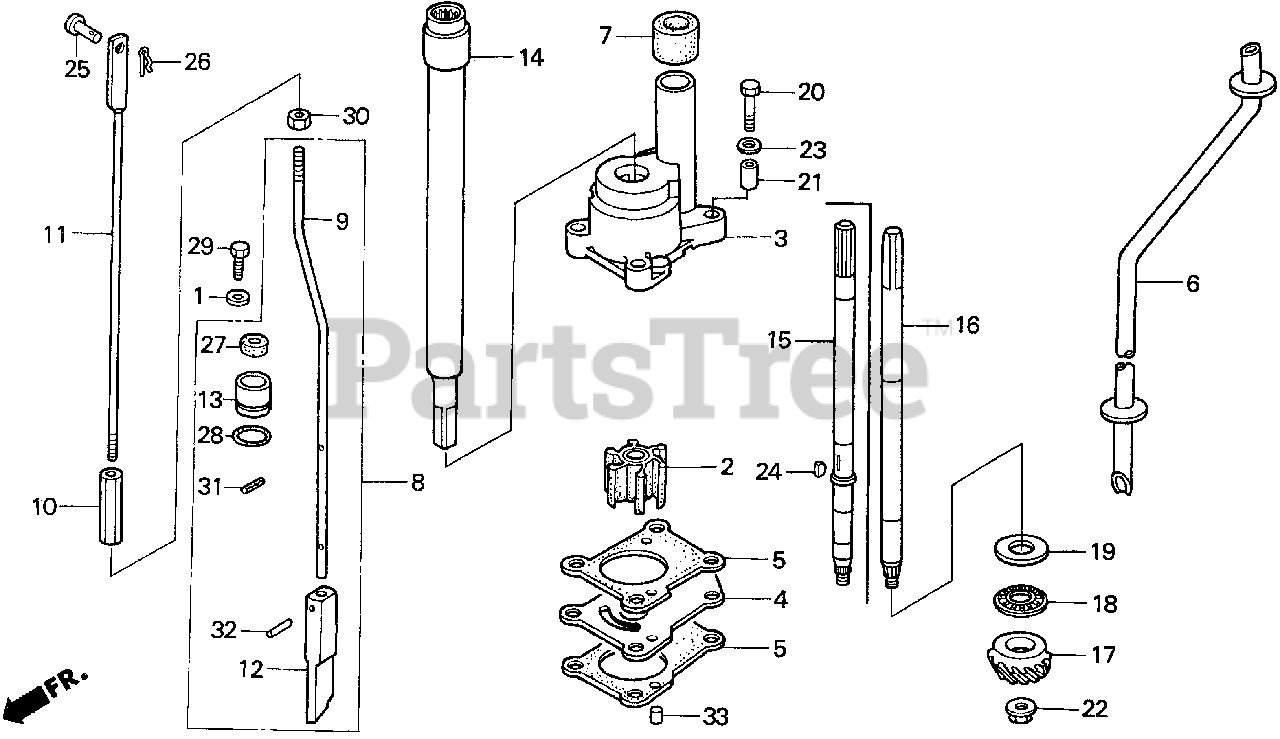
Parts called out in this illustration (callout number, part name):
1	WASHER, PLAIN (6MM)
1	WASHER, FRICTION
2	IMPELLER, PUMP
3	HOUSING, IMPELLER
4	COVER, IMPELLER
5	GASKET, IMPELLER
6	TUBE, WATER (UL)
7	RING, WATER TUBE SEAL
8	ROD B, SHIFT (UL)
9	ROD B, SHIFT (UL)
10	JOINT, SHIFT ROD
11	ROD A, SHIFT
13	HOLDER, SEAL
15	SHAFT, VERTICAL (UL)
17	PINION (13T)
18	WASHER A, THRUST BEARING (2.00MM)
19	WASHER A, THRUST BEARING (3.00MM)
19	WASHER B, THRUST BEARING (3.03MM)
19	WASHER C, THRUST BEARING (3.06MM)
19	WASHER D, THRUST BEARING (3.09MM)
20	BOLT, HEX. (6X28)
21	COLLAR B, DISTANCE
22	NUT, SPECIAL FLANGE (8MM)
23	WASHER, PLAIN (6MM)
24	KEY, WOODRUFF (16X12)
25	PIN (5X28)
26	PIN, SPLIT (2.0)
27	SEAL, WATER (6MM)
28	O-RING (15X2.5)
29	BOLT, HEX. (6X12)
30	NUT, HEX. (6MM)
31	PIN, SPRING (2.5X12)
32	ROLLER (2.5X11.8)
33	ROLLER (4X10)
